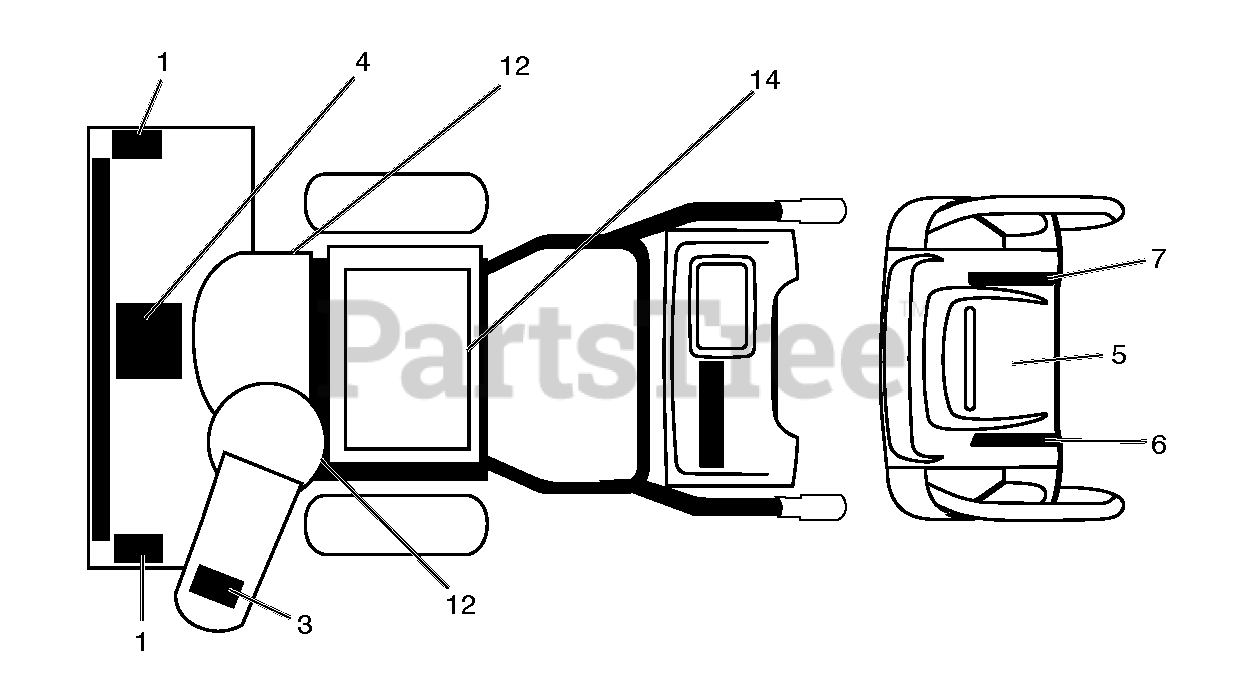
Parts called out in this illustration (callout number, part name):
1	DECAL.AUGER.SAFETY.
3	DECAL.CHUTE.SAFETY.
4	DECAL.AUGER."
5	DECAL.CONSOLE.INSTRUCTION
6	DECAL.CONS.LT.WO/DEFL
7	DECAL.CONS.RT.SPD/LEV/PWRST
12	DECAL.BELT.GUARD.
14	DECAL.FENDER
